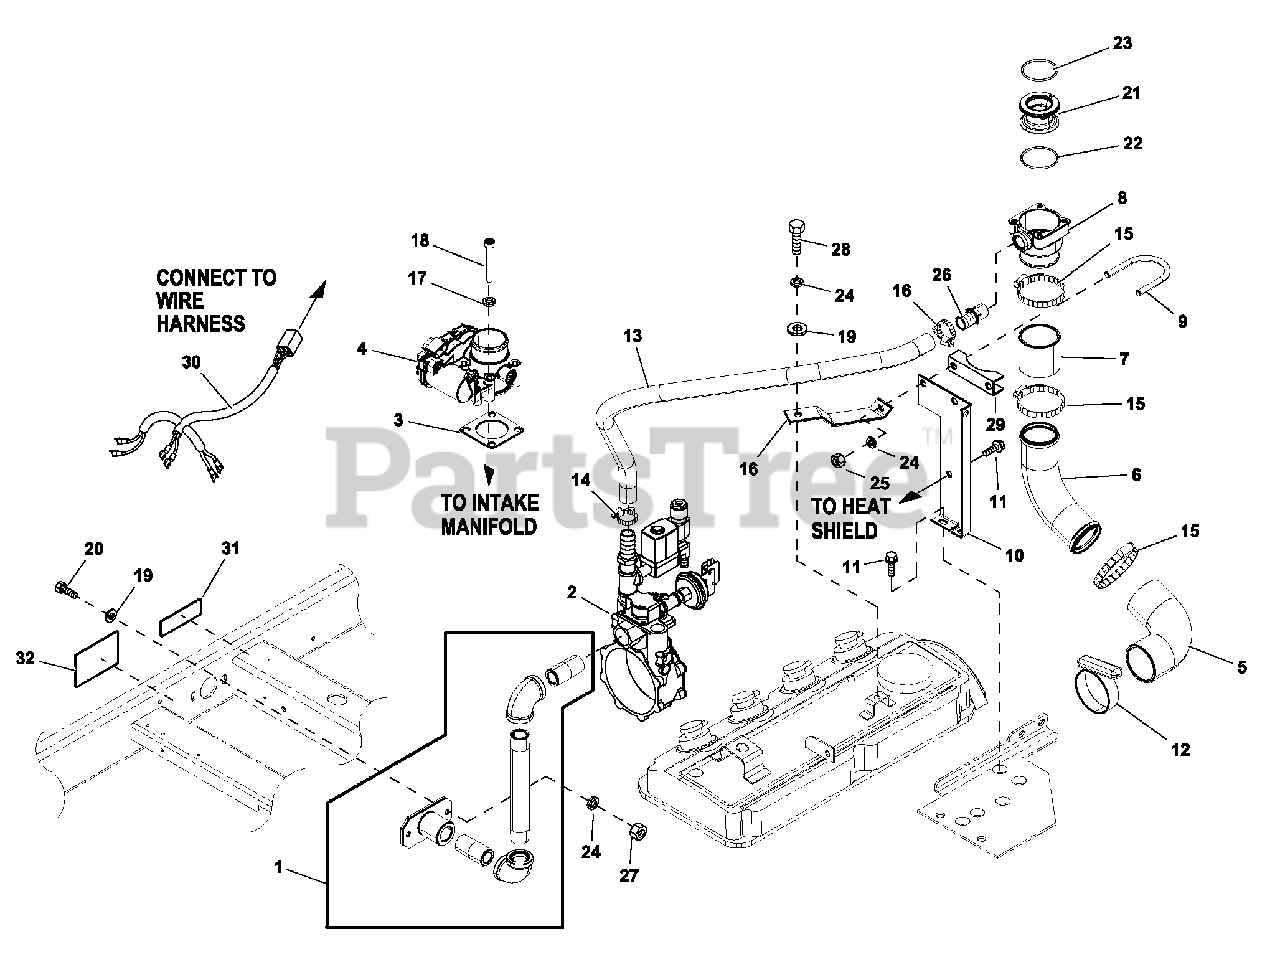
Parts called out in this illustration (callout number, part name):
1	ASSY RGLTR INLET NPT FITTINGS
2	REGULATOR ASSY 2.4L 36KW
3	GASKET, BOSCH 32 & 40
4	ACTUATOR BOSC H 40, GOVERNOR
5	ELBOW RUBBER 90 2" ID
6	INTAKE TUBE 2.4L G2 36KW
7	H OSE COOL 2IN ID 20R4 (3FT)
8	MIXER ACTUATOR
9	BOLT U 5/16-18X2.09
10	BRACKET INTAKE MANIFOLD
11	SCREW H H TTM6-1.0X12
12	CLAMP CNST TENSION 1.75-2.625
13	H OSE 3/4 ID LPG & NG (35"LG)
14	CLAMP H OSE #8 .53-1.00
15	CLAMP H I TORQUE 1.75 - 2.625
16	BRACKET-INTAKE REINFORCEMENT
17	WAS H ER LOCK M6-1/4
18	SCREWS H C M6-1.0X45
19	WAS H ER FLAT 5/16-M8 ZINC
20	SCREW H H C M8-1.25 X 20 G8.8
21	VENTURI TH ROTTLE 24MM
22	O-RING 47.625 ID X 2.38 WIDT H
23	O-RING 45.63 ID X 2.62 WIDT H
24	WAS H ER LOCK M8-5/16
25	NUT H EX 5/16-18 STEEL
26	BARBED STR 1/2NPTX3/4
27	H EX NUT-METRIC
28	SCREW H H C M8-1.25 X 16 G8.8
29	SADDLE 2 INC H
30	HARN FUEL JUMPER SINGLE REG
31	DECAL INLET PRESSURE
32	DECAL FUEL INLET
